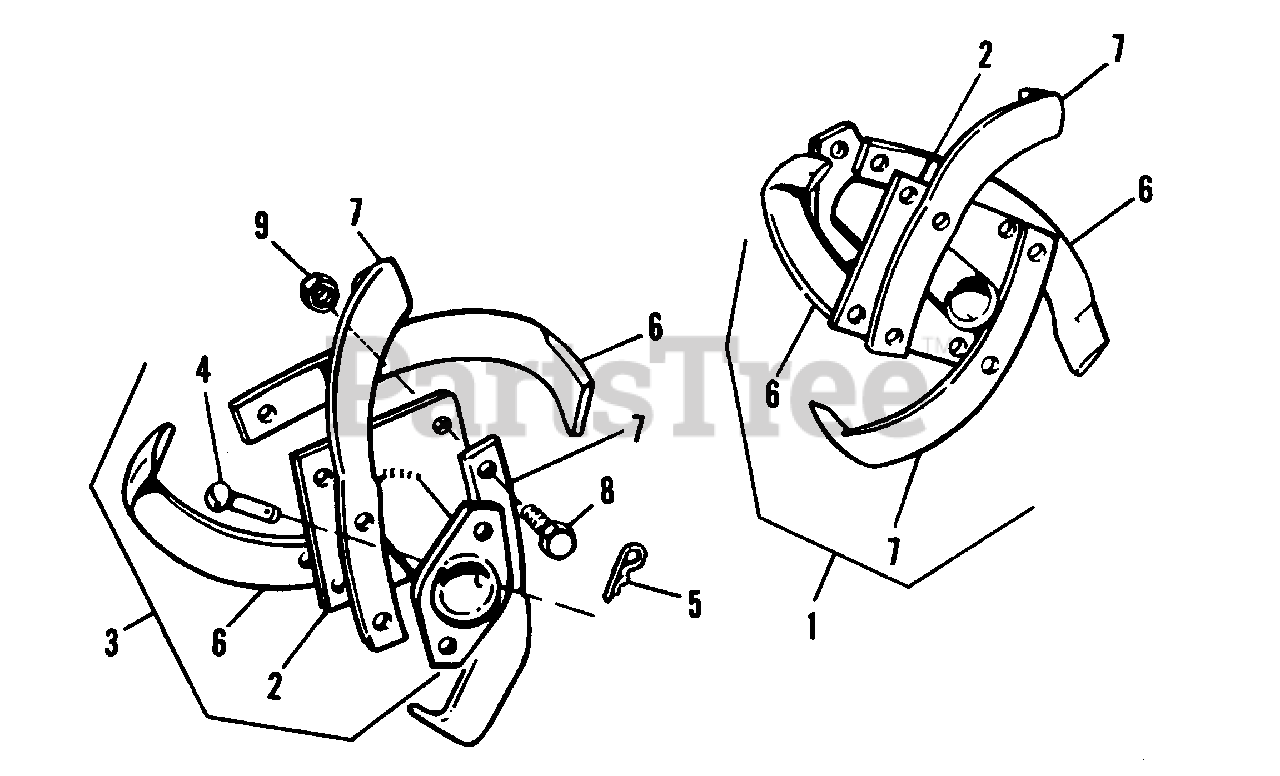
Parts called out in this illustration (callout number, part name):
1	EXTENSION ASSY, Tine Blade, L.H. Complete
2	PLATE ASSY, Tine Extension
3	EXTENSION ASSY, Tine Blade, R.H. Complete
4	PIN
5	CLIP, Spring
6	BLADE, Tine, L.H.
7	BLADE, Tine, R.H.
8	CAPSCREW, Hex, 7/16-20 x 1-1/4
9	NUT, Hex, Full, 7/16-20
